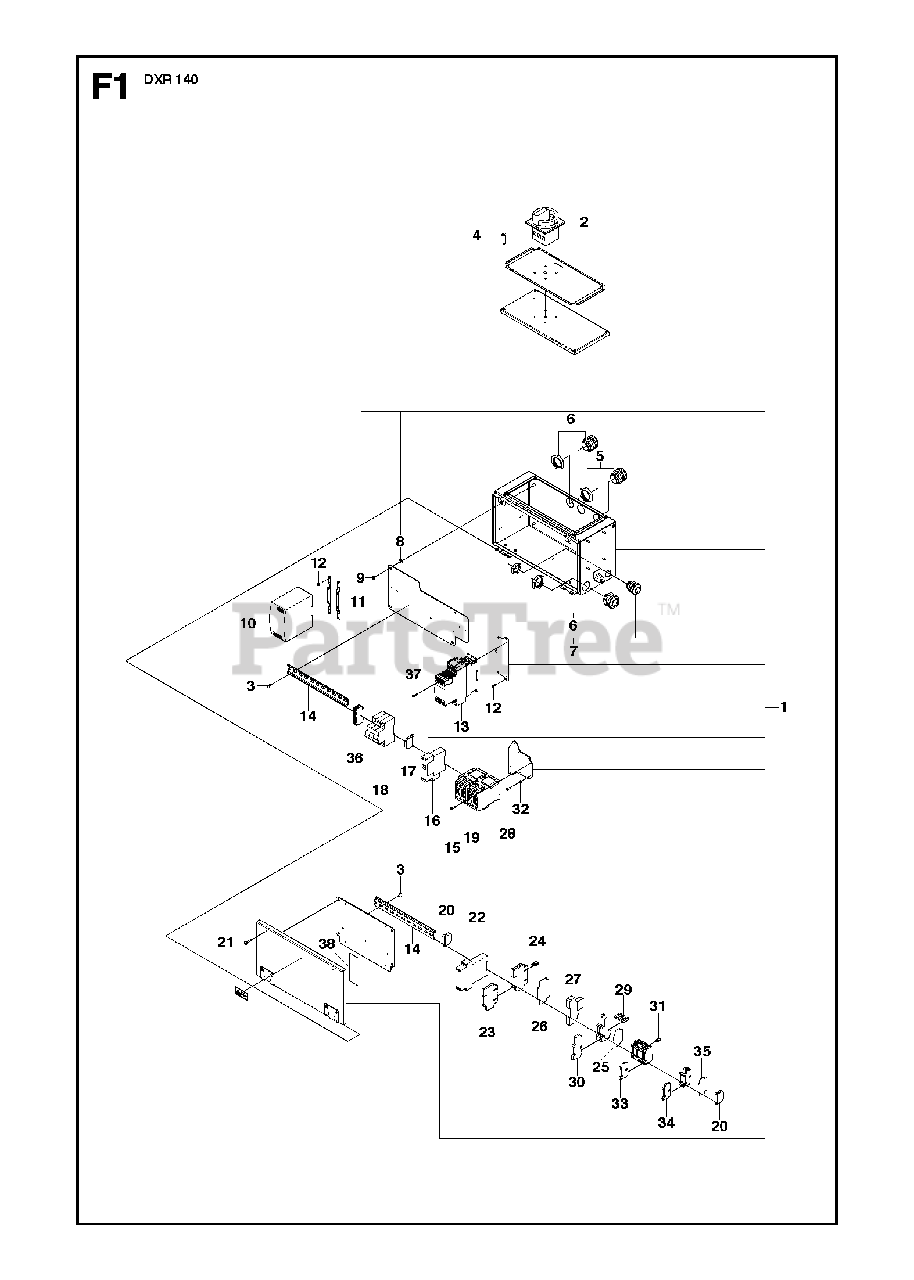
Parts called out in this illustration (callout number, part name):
4	SCREW EHHM
16	RELAYK1, Phase sequence relay
22	RELAYB1, Safety relay
